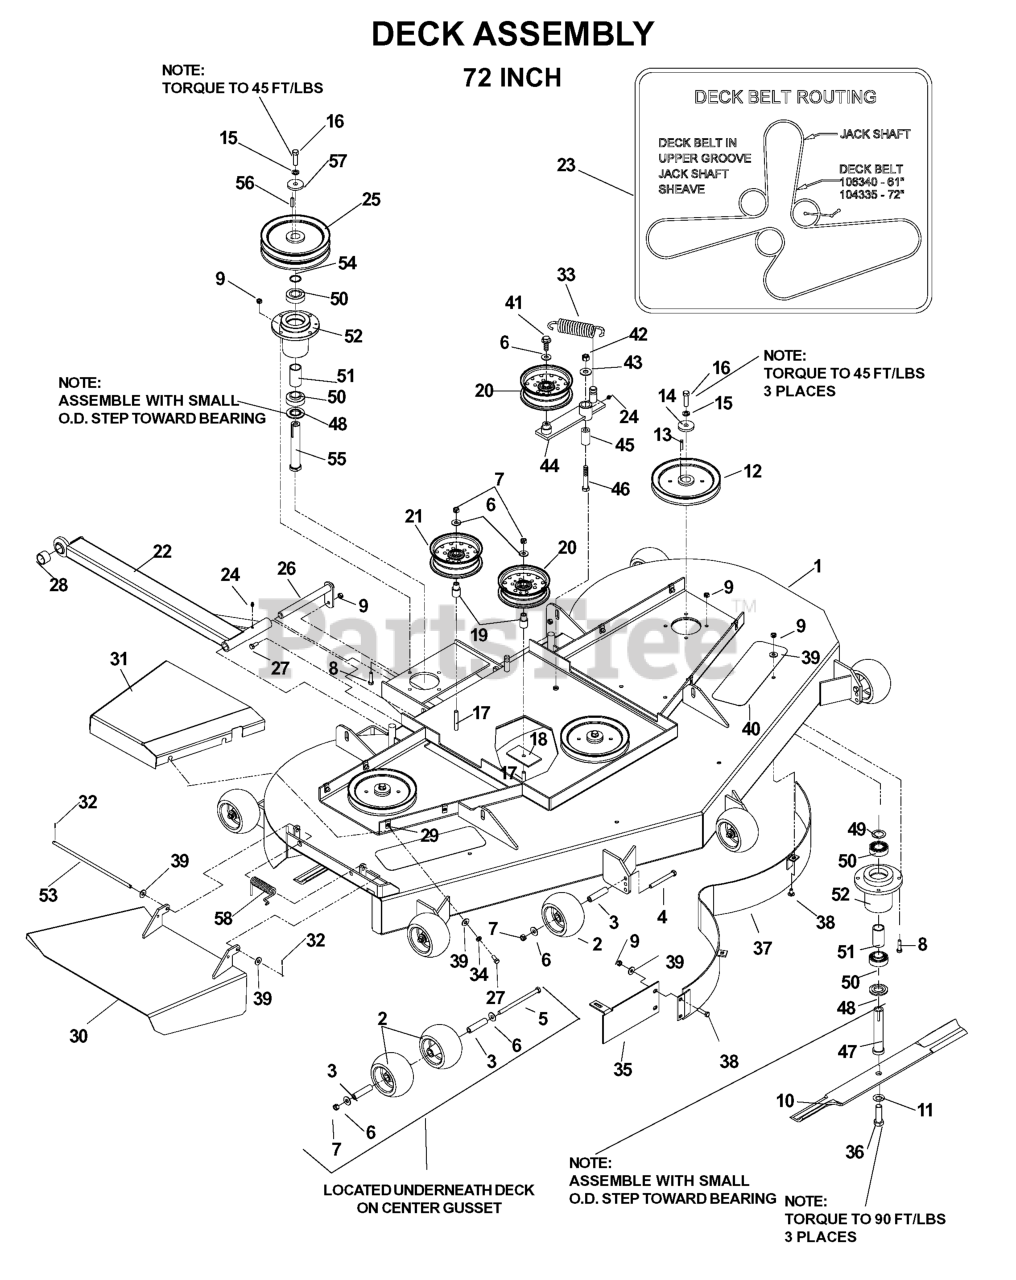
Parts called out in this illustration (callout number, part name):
1	DECK W/DECALS 72" HUS
2	ANTI-SCALP ROLLER
4	HCS 3/8C X 3 1/2
5	BOLT 3/8 X 6" GRD 8
6	WASHER 3/8 FLAT
7	NUT 3/8C CENTERBLOCK
8	HCS 5/16C X 1 1/4
9	NUT 5/16C CENTERLOCK
10	BLADE OEM - 25"
11	BELLEVILLE SPRING WASHER
13	KEY 1/4 SQ X 1 1/8
14	SPINDLE WASHER
15	WASHER 7/16 LOCK
16	HCS 7/16F X 1 1/2
17	HCS 3/8C X 3
18	SUPPORT PLATE
19	IDLER BUSHING
20	IDLER PULLEY
21	IDLER PULLEY (TALL)
22	STRUT WELDMT - R.H
23	BELT, DECK
24	ZERK
25	SHEAVE WSL
26	PIN WELDMENT
27	HCS 5/16C X 3/4
28	SPACER, STRUT
29	U-CLIP 5/16-18 NUT RETAINER
30	DISCHARGE CHUTE
31	ORANGE-R.H BELT SHLD 72"
32	COTTER PIN
33	DECK SPRING
34	WASHER.LOCK.HVY.HLCL.SPR.5/16
35	BAFFLE/CENTER-FLAT BLK
36	HEX SCREW-5/8F X 2 GR8
37	BAFFLE/CENTER-CURVED
38	CARRIAGE BOLT 5/16C X 5/8"
39	WASHER 5/16 FLAT
40	ANTI-SKID PAD
41	4CS 3/8C X 1 SERRATED HEAD
42	NUT 1/2-13 HEX NYLOC ZD
43	WASHER 1/2 FLAT
45	PIVOT BUSHING
46	HCS 1/2C X 3 1/4
47	SPINDLE SHAFT
48	COMBO SPACER
49	BUSHING.MACHINE.18.GAUGE
50	BEARING
52	HOUSING, DIE CAST
53	PIN 5/16 X 11-1/2 PIVOT SPEC
54	BUSHING.MACHINE.18.GAUGE
55	SPINDLE SHAFT
56	KEY 1/4 SQ X 1 1/8
57	SPINDLE WASHER
58	SPRING, TORTION
539107751	STRUT WELDMT, L.H.
539108317	72 ORANGE L.H BLT SHLD
